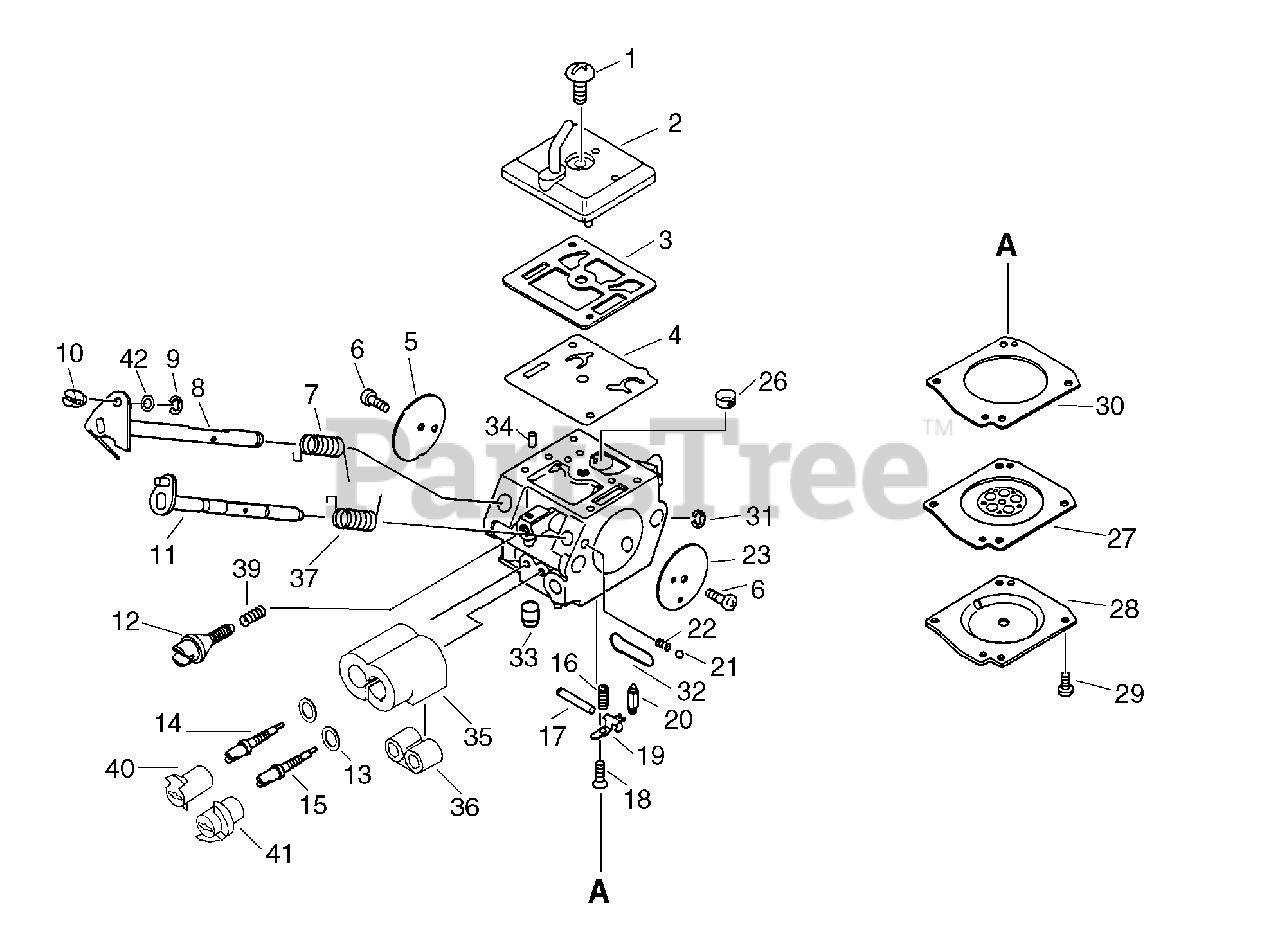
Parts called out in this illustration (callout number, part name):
2	COVER, PUMP
3	GASKET, PUMP
4	DIAPHRAGM, PUMP
5	VALVE, THROTTLE
6	SCREW 3×4.5
7	SPRING, THROTTLE RETURN
8	SHAFT ASSY, THROTTLE
11	SHAFT, CHOKE
12	SCREW, THROTTLE ADJUST
14	SCREW, IDLE ADJUST
15	SCREW, MAIN ADJUST
16	SPRING, COIL
17	PIN, METERING LEVER
19	LEVER, METERING
20	VALVE, INLET NEEDLE
21	BALL, CHOKE
22	SPRING, THROTTLE FRICTION
23	VALVE, CHOKE
26	STRAINER
27	DIAPHRAGM
28	COVER, DIAPHRAGM
30	GASKET, METERING DIAPHRAGM
32	PLUG, WELCH
33	NOZZLE, CHECK VALVE
34	PIECE, FRICTION
35	CAP, LIMITER
36	SCREW, ADJUSTER
37	SPRING, CHOKE RETURN
39	SPRING, IDLE ADJUST
40	CAP, LIMITER
41	CAP, LIMITER
